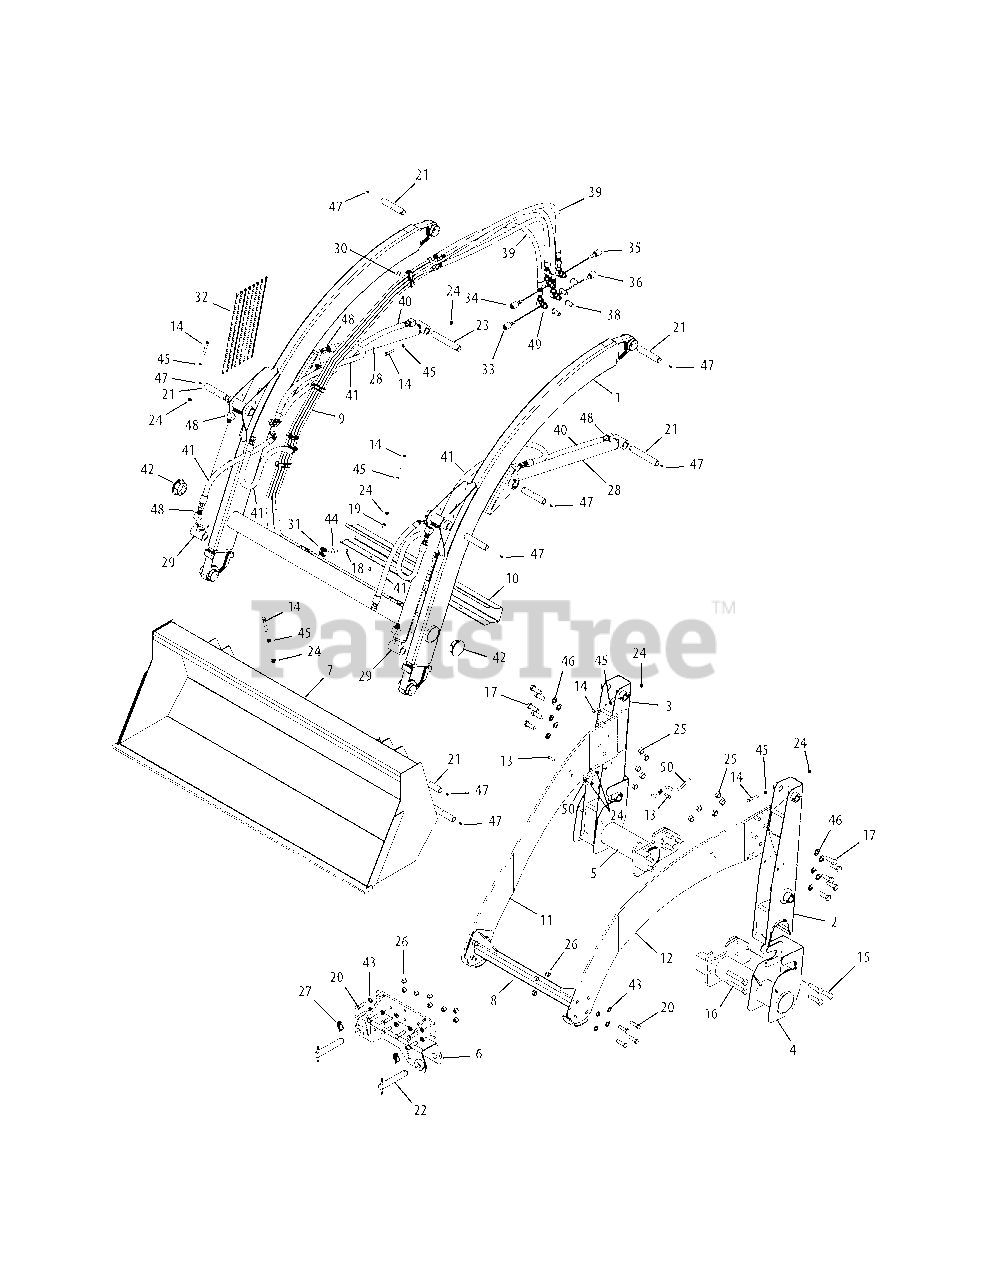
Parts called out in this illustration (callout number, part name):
1	Arm Assembly, Main
2	Support Assembly, Vertical, LH
3	Support Assembly, Vertical, RH
4	Mount Assembly, LH
5	Mount Assembly, RH
6	Receptacle Assembly, Loader
7	Bracket Assembly, Loader
8	Bracket Assembly, Hitch Loader
9	Tube Assembly, Loader
10	Cover, Tube, Loader
11	Bracket, Loader, RH
12	Bracket, Loader, LH
13	Hex Screw, 5/16-18, 1.00, Gr5
14	Hex Screw, 5/16-18, 2.25, Gr5
15	Screw, M16-20, 60mm
16	Screw, M16-2.00, 100mm
17	Hex Screw, 5/8-11, 1.75, Gr8
18	Hex Screw, 1/4-20, 2.50, Gr5
19	Screw, Self-tapping 1/4-20 x .625
20	Hex Screw, 1/2-13, 1.75, Gr5
21	Pin, 1"OD, 5", Grease, w/ 5/16" Hole
22	Pin, 1"OD, w/ Handle
23	Pin, 1"OD, 6.5", Grease, 5/16" Hole
24	Nut, Flange Lock, 5/16-18, GrF,
25	Nut, Flange, 5/8-11 Top Lock
26	Nut, Hex Lock, 1/2-13, GrB, Nylon
27	Pin, Klik, .245 Dia X 1.406
28	Cylinder, 28", 1.625" Bore
29	Cylinder, 24", 2" Bore
30	Nut, Push, .25 Id X .50 OD
31	Clamp, Tube
32	Cable Tie, 18"
33	Plug, Female, Hydraulic Coupler, Green
34	Plug, Female, Hydraulic Coupler, Blue
35	Plug, Female, Hydraulic Coupler, Yellow
36	Plug, Female, Hydraulic Coupler, Red
38	Coupling, Hydraulic, Male Sae, 3/8
39	Hose, Hydraulic, 1/2 ORB, 3/8 ORFS
40	Hose, Hydraulic, 3/8 ORFS-3/8 ORFS 90
41	Hose, Hydraulic, 3/8 ORFS-3/8 ORFS 90
42	Plug, Tube, Round
43	Washer, Flat, .535x.930x.090
44	Washer, Flat, .285 X 1.25 X .06
45	Washer, Flat, .330 x .630 x .064
46	Washer, Flat, .640x1.120x.125
47	Grease Fitting
48	Fitting, Straight, 3/8 ORFS X 3/8 ORB
49	Fitting, Hydraulic, 90, -8 ORB X -8 FORB
